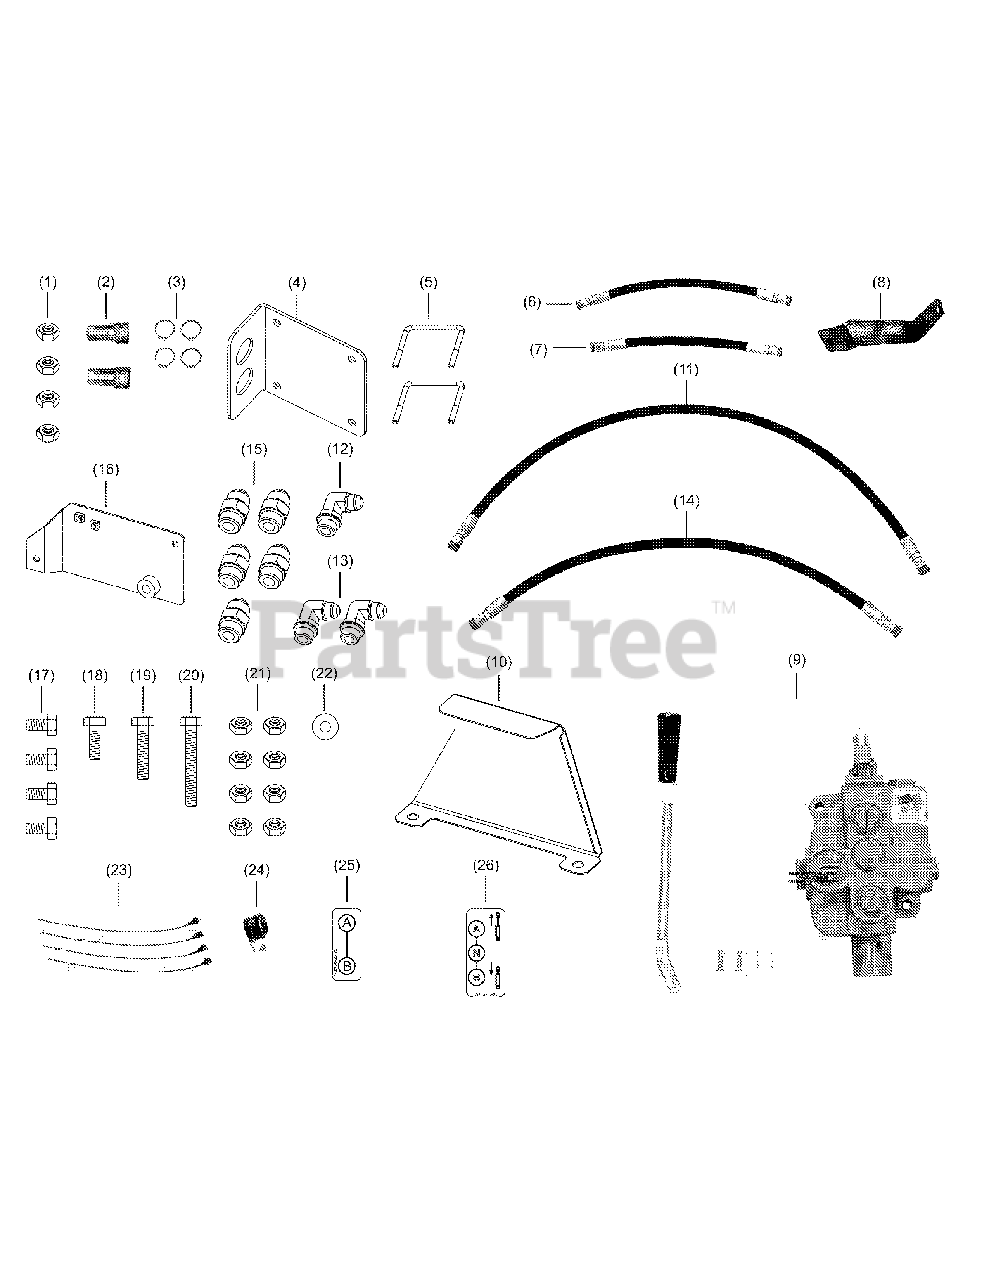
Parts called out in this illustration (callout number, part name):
2	COUPLER, QUICK 3/8F
4	BRACKET, COUPLER
6	VALVE HOSE, PORT A
7	VALVE HOSE, PORT B
8	SUPPORT, BRACKET
9	REAR REMOTE VALVE
11	VALVE HOSE, INLET
14	VALVE HOSE, OUTLET
16	BRACKET, REAR REMOTE
17	BOLT 8 × 16 mm (L: 0.64 in.)
18	BOLT 8 × 25 mm (L: 1.01 in.)
19	BOLT 8 × 40 mm (L: 1.16 in.)
20	BOLT 8 × 60 mm (L: 2.4 in.)
25	LABEL, REAR REMOTE VALVE PORT 1
26	LABEL, REAR REMOTE VALVE LEVER
